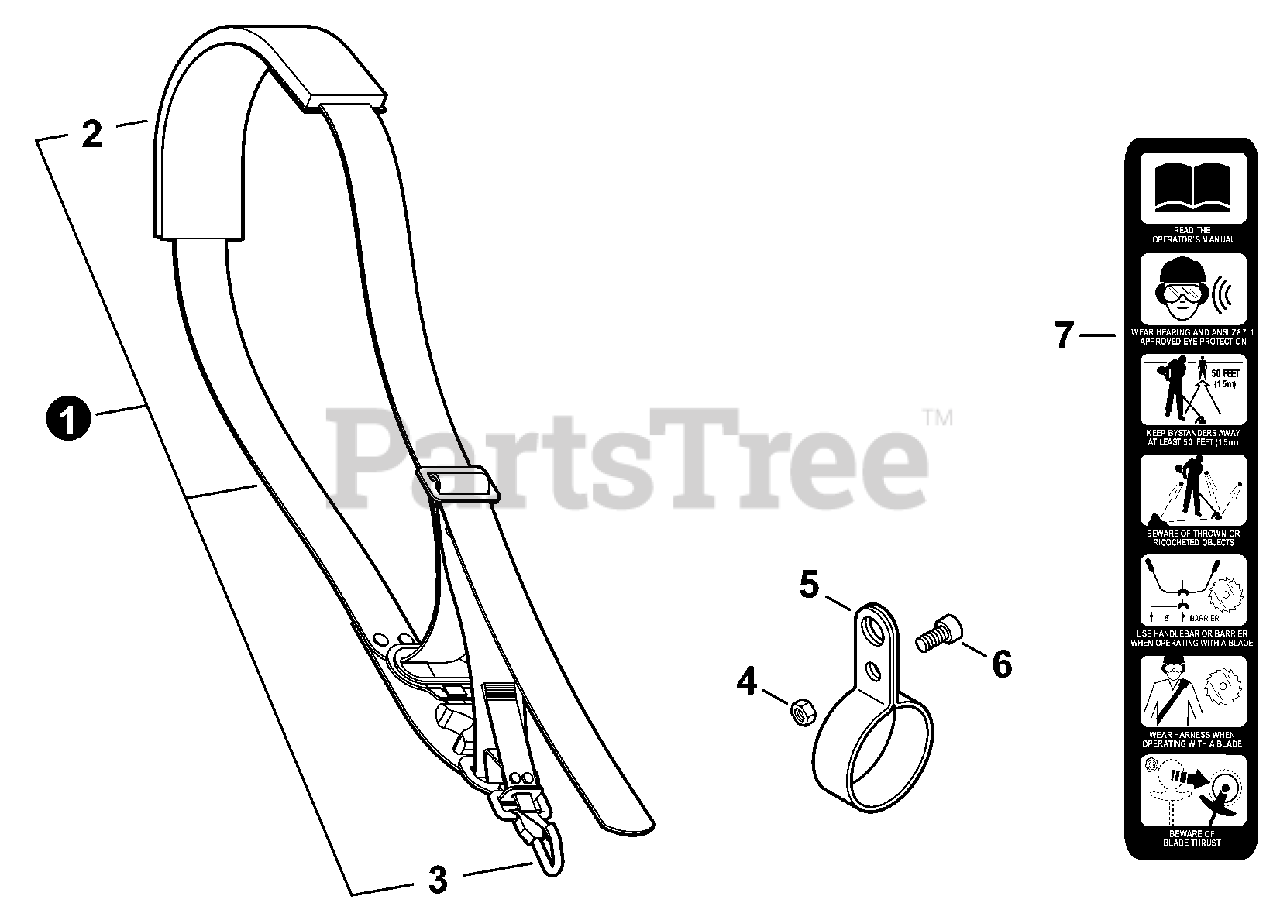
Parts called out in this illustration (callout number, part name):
1	HARNESS ASSY, SHOULDER
2	PAD, SHOULDER
3	HOOK, SNAP
4	NUT M5
6	BOLT 5×12
7	LABEL, CAUTION (BLADE CAPABLE)
